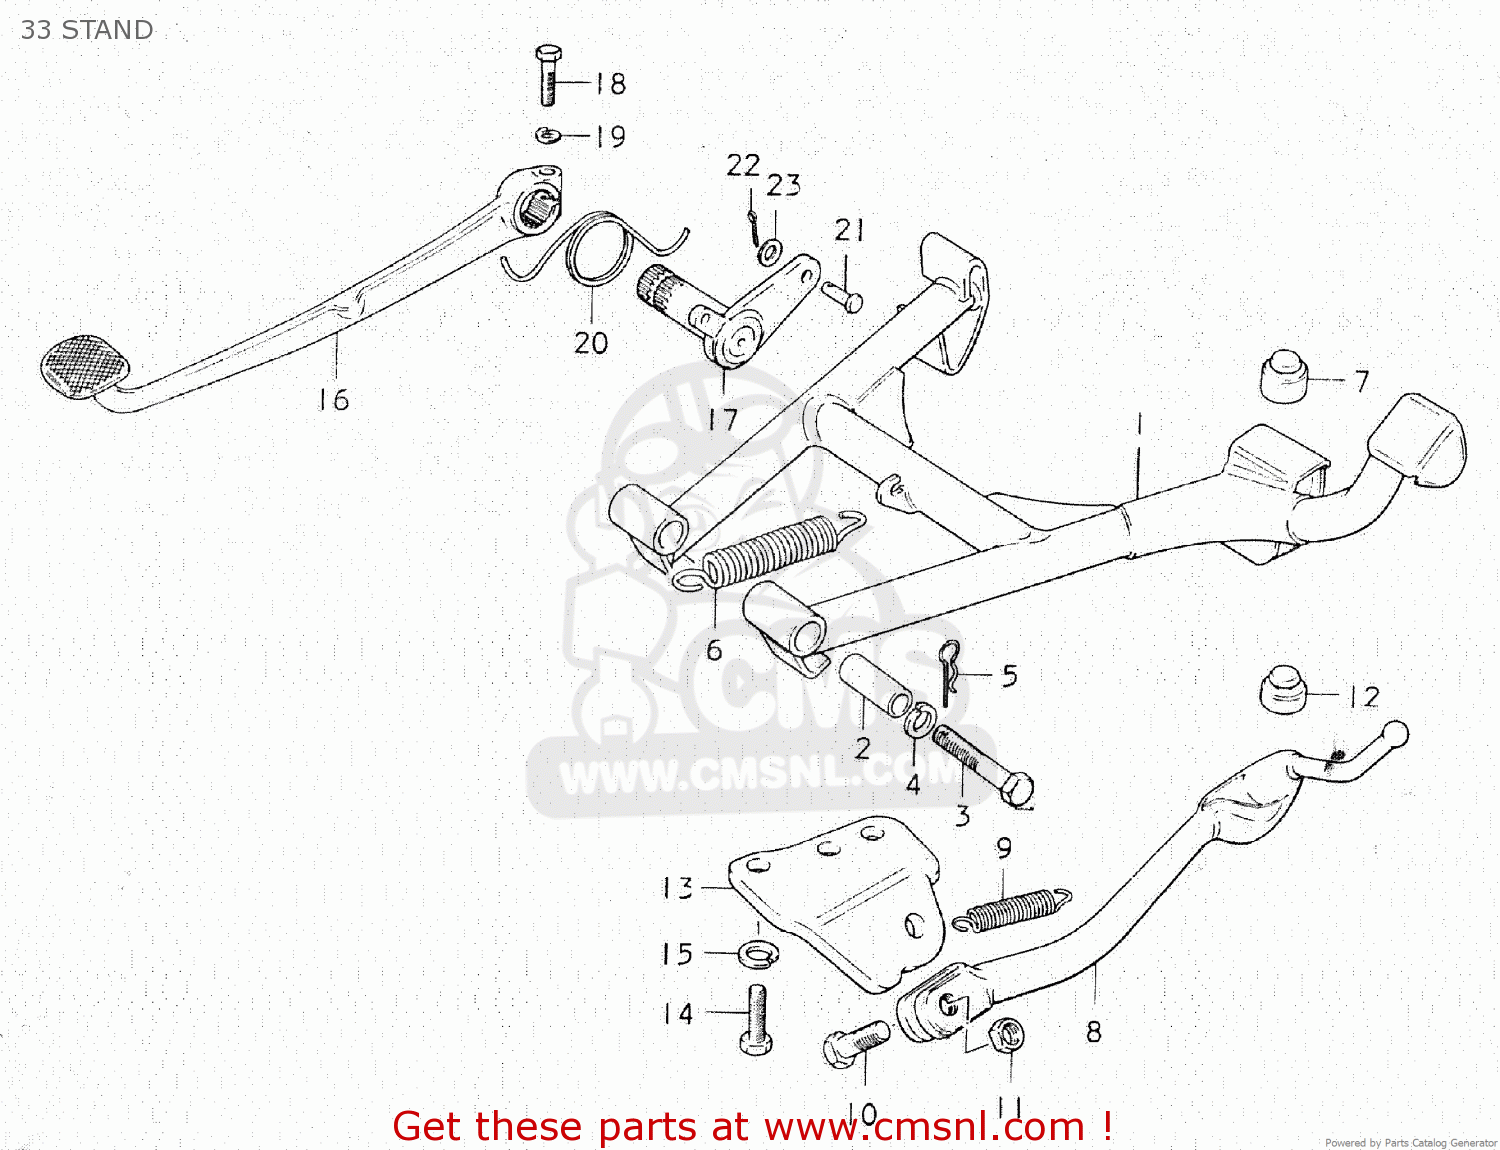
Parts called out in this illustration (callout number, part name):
1	STAND,CENTER
2	SPACER(10X16X38.8)
3	BOLT
4	LOCK WASHER
5	CLIP
6	SPRING
7	CUSHION
8	STAND,PROP
9	SPRING
10	BOLT(10X30)
11	NUT
12	CUSHION(11.5X22X20)
13	BRACKET,SIDE STAND
14	BOLT
15	LOCK WASHER
16	PEDAL,BRAKE
17	ARM,BRAKE PEDAL ROD
18	BOLT
19	LOCK WASHER
20	SPRING
21	PIN
22	PIN
23	WASHER
